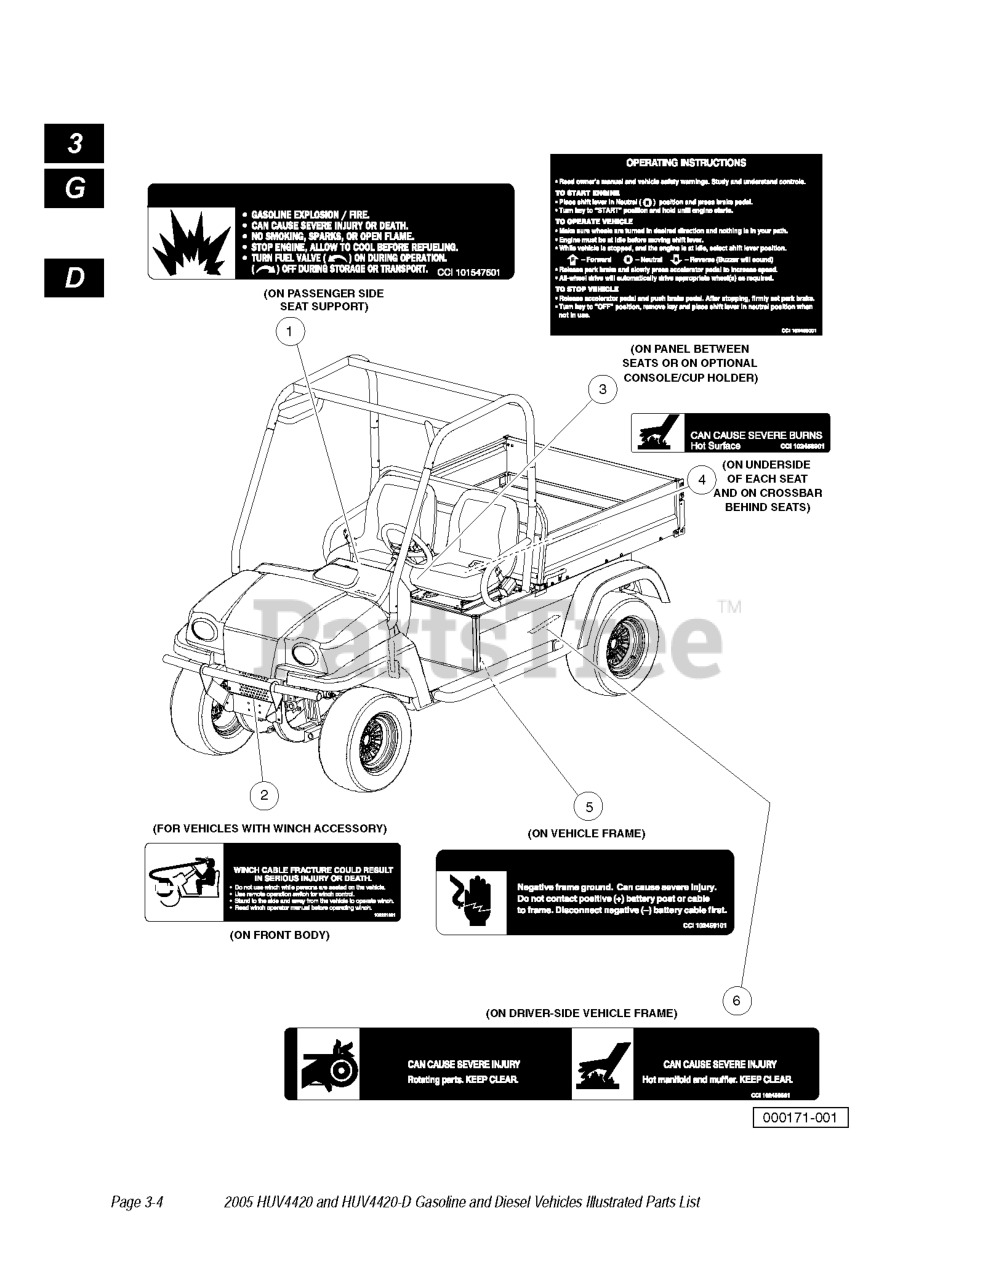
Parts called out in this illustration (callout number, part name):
1	DECAL, WARNING - GASOLINE FUEL
2	DECAL-WINCH KIT
3	DECAL, OPER INSTR AWD GAS
4	DECAL, WARNING HOT SURFACE
5	DECAL, WARNING GROUND
6	DECAL, WARNING ROTATE/HOT
